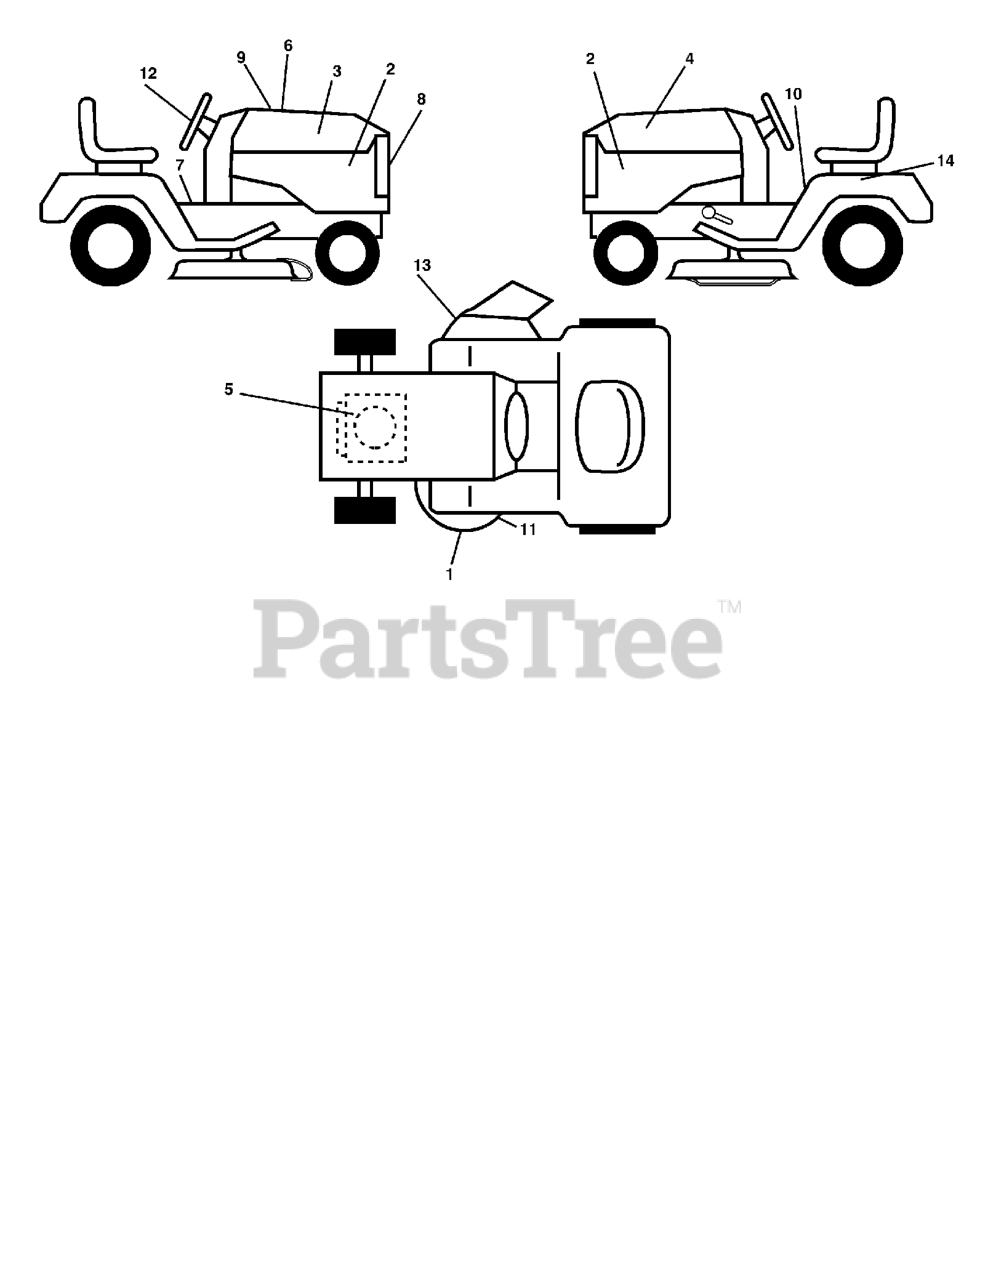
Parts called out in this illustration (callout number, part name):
1	DECAL, MOWER HEAVY DUTY
2	DECAL
3	DECAL, HOOD RH
4	DECAL, HOOD LH
5	DECAL
6	DECAL HOOD CUST. RESP.
7	DECAL SET
8	DECAL
9	DECAL
10	DECAL FENDER DANGER
11	DECAL V-BELT SCHEMATIC
12	DECAL.STEERING.HUSQ.BLUE
13	DECAL.WARN.KEEP.HAND.AWAY
14	DECAL BTRY SYMBOLS
